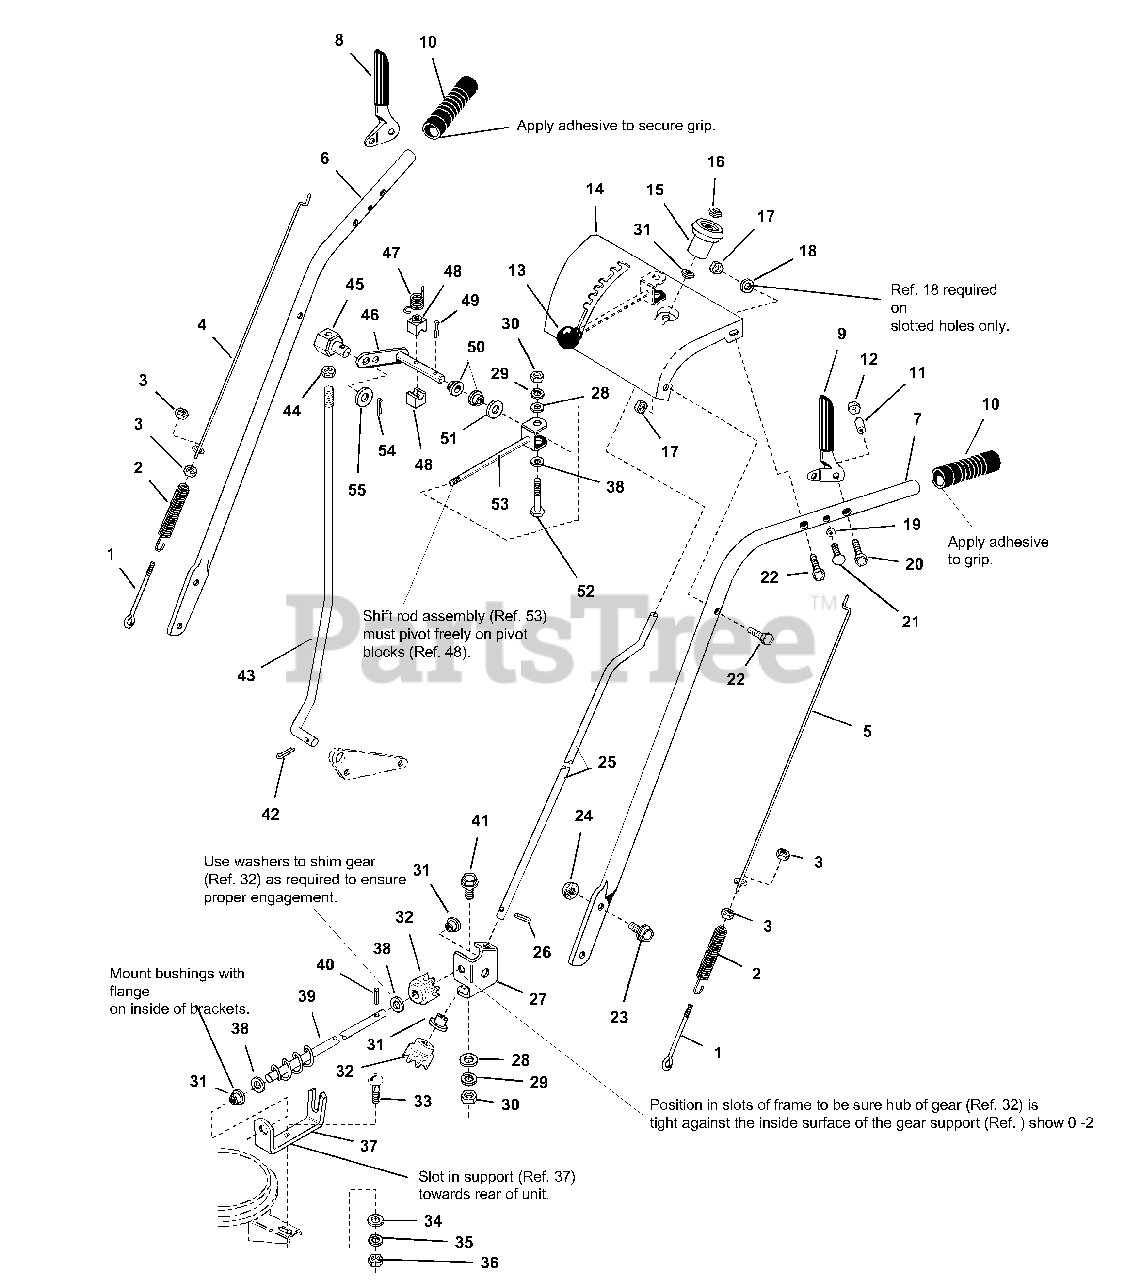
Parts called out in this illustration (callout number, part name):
2	SPRING, Extension
3	NUT, Hex, #10-24 R.H.
4	CLUTCH ROD, Traction Drive
5	CLUTCH ROD, Auger Drive
6	HANDLE, R.H.
7	HANDLE, L.H.
8	LEVER, Auger Clutch, R.H.
9	LEVER, Traction Drive Clutch, L.H.
10	GRIP, Black Vinyl
11	SPACER, Large
12	NUT, Hex, Centerlock, 1/4-20
13	KNOB, Int. thrd., 3/8-16
14	DASHBOARD & SUPPORT ASSY.
15	KNOB, Chute Control Spinner
16	NUT, Push, 3/8
17	NUT, Hex Lock, 5/16-18
18	WASHER, Flat 5/16
19	SPACER, Small
20	CAPSCREW, Hex Hd., 1/4-20 x 1-1/2
21	SCREW, Taptite, Pan Hd., Torx, 1/4-20 x 3/4
22	CAPSCREW, Hex Hd. 5/16-18 x 1-1/2
23	SCREW, Hex, Flange Whizlock, 5/16-18 x 1/2
24	NUT, Hex, Flange Whizlock, 5/16-18
25	ROD, Chute Control
26	PIN, Spring, 1/8 x 3/4
27	SUPPORT, Gear
28	WASHER, Flat 1/4
29	LOCKWASHER, 1/4
30	NUT, Hex Hd., 1/4-20
31	BUSHING, Nylon
32	GEAR, Steel, Universal
33	CARRIAGE BOLT, 5/16-18 X 3/4
34	WASHER, Flat 5/16
35	LOCKWASHER, 5/16
36	NUT, Hex, 5/16-18
37	BRACKET, Worm Support
38	WASHER, Flat 3/8
39	WORM ASSEMBLY
40	PIN, Spring
41	BOLT, Rd. Hd., 1/4-20 X 3/4
42	PIN, Cotter
44	NUT, Jam, 3/8-16
46	ROD & ARM ASSY., Pivot
47	SPRING, Torsion
48	BLOCK, Pivot
49	PIN, Cotter
51	WASHER
52	CAPSCREW, Hex Hd. 1/4-20 x 2 1/4 G5
53	ROD & CLEVIS ASSY.
54	CLIP, Hair Pin
55	WASHER
